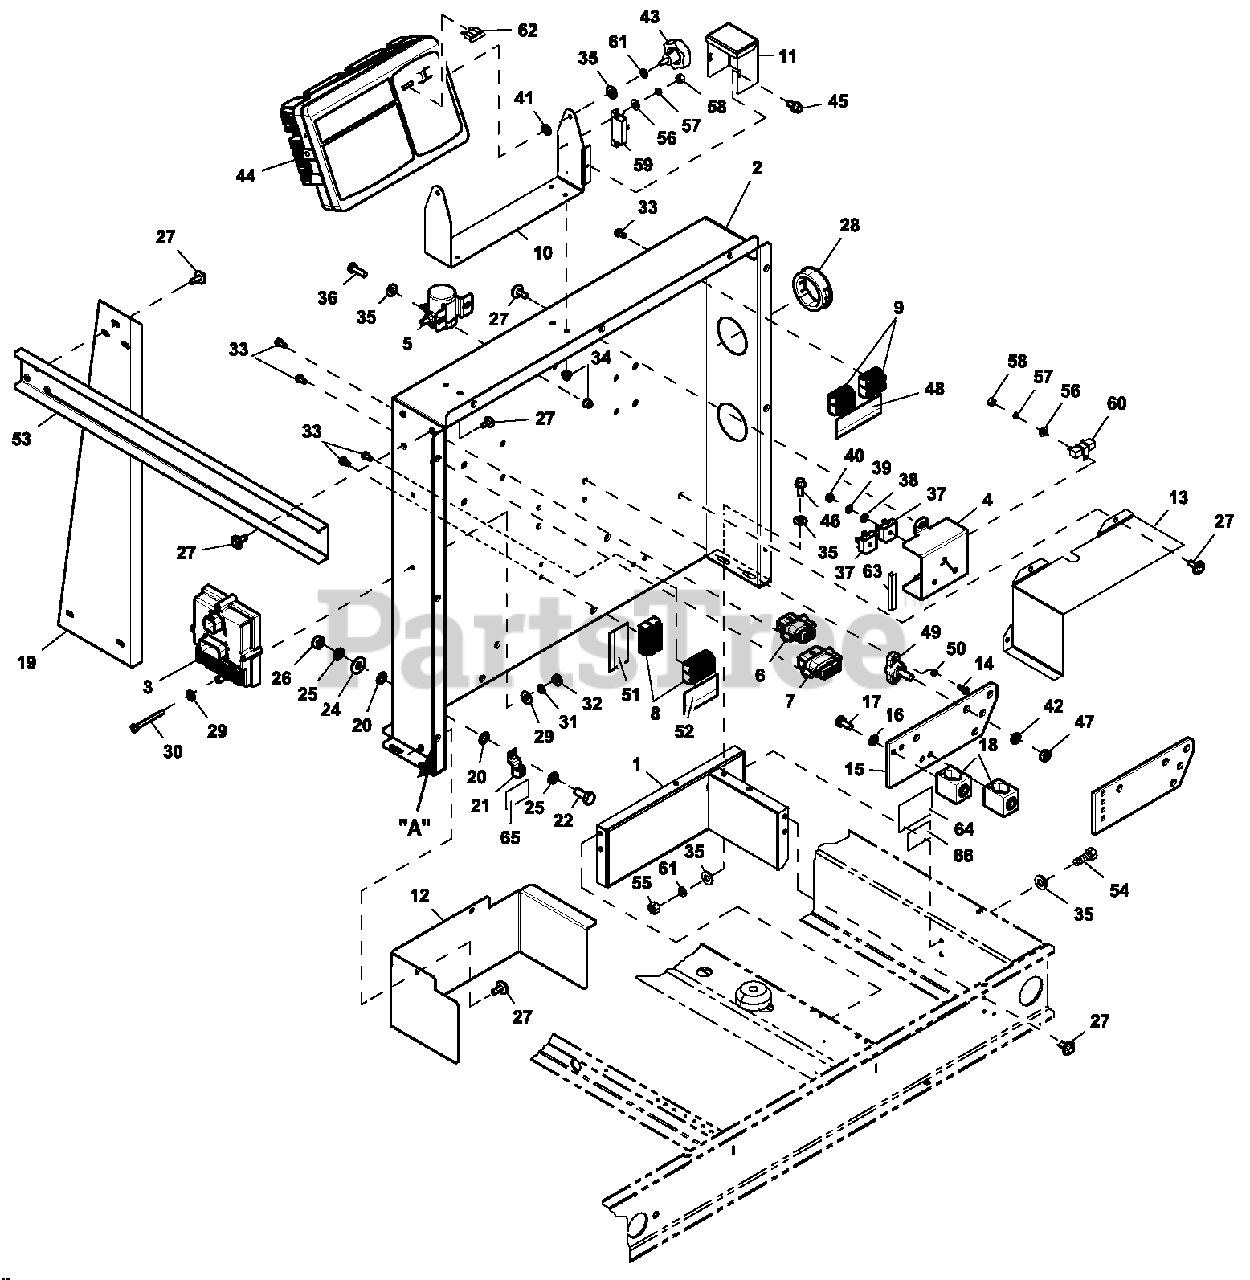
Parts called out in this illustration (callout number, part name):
1	CHAN ASSY CB SUPPORT
2	PANEL CB CONNECTION
3	ASSY PROG 2010 IGN MOD 10CYL
4	COVER VOLTAGE SHIELD
5	RELAY SOLENOID 12VDC PNL MNT
6	MX150L SLRRMNT 22-18 8P W/O GA
7	MX150L SLRRMNT 22-18 12P W/OGA
8	TERM BLOCK 4P UL 12-20AWG
9	TERM BLOCK 3P UL 12-20AWG
10	BRACKET GIMBAL CONTROL PNL
11	COVER DPE BREAKER NEXUS
12	CHUTE C5 RAW
13	SHIELD HIGH/LOW C5
14	SCREW PHTT M4-0.7 X 12 ZP
15	BUS BAR NEUTRAL BLOCK
16	WASHER LOCK M6-1/4
17	SCREW HHC 1/4-28 X 5/8 .625TH
18	LUG SLDLSS 600/250-1/0X1/4-28
19	CHANNEL, SUPPORT
20	WASHER LOCK EXT 7/16 STL
21	LUG SLDLSS 3/0-+4X 13/32 CU
22	SCREW HHC M10-1.5 X 25 C8.8
24	WASHER FLAT 3/8-M10 ZINC
25	WASHER LOCKM10
26	NUT HEX M10-1.5 G8 YEL CHR
27	SCREW HWHT M6-1 X 16 N WA Z/JS
28	BUSHING SNAP SB-2.5-31
29	WASHER FLAT #10 ZINC
30	SCREW PPHM # 1 0 -3 2X 2
31	WASHER LOCK #10
32	NUT HEX #10-32 STEEL
33	SCREW HHSP #10 X 3/8 HI-LOW
34	NUT FLANGE M6-1.0 NYLOK
35	WASHER FLAT 1/4-M6 ZINC
36	SCREW HHC M6-1.0 X 20 C8.8
37	DIODE BRIDGE 1P 35A 1000V
38	WASHER FLAT M5
39	WASHER LOCK M5
40	NUT HEX M5-0.8 G8 CLEAR ZINC
41	WASHER NYLON .257
42	WASHER LOCK 3/8
43	KNOB M6-1.0 CONTROL PANEL
44	ASSY CTRL PROGRAMMED
45	SCREW HHTT M4-0.7 X 8 ZP
46	SCREW HHTT M6-1.0 X 16 ZYC
47	NUT HEX 3/8-16 STEEL
48	DECAL CONBOX TB1 CONNECTIONS
49	JUNCTION BLOCK 3/8-1
50	WASHER LOCK#8-M4
51	DECAL CUSTOMER POWER CONNECT
52	DECAL CUSTOMER CONTROL CONNECT
53	CHANNEL, BRACE
54	SCREW HHC M6-1.0 X 1 6 C8.8
55	NUT HEX M6-1.0 G8 CLEAR ZINC
56	WASHER FLAT M3
57	WASHER LOCK M3
58	NUT HEX M3-0.5 G8 CLEAR ZINC
59	CB 3A 1P ETA 46-500-P
60	RES WW 50R 5% 25W QK CONN
61	WASHER LOCK M6-1/4
62	FUSE ATO TYPE 7.5AMP (BROWN)
